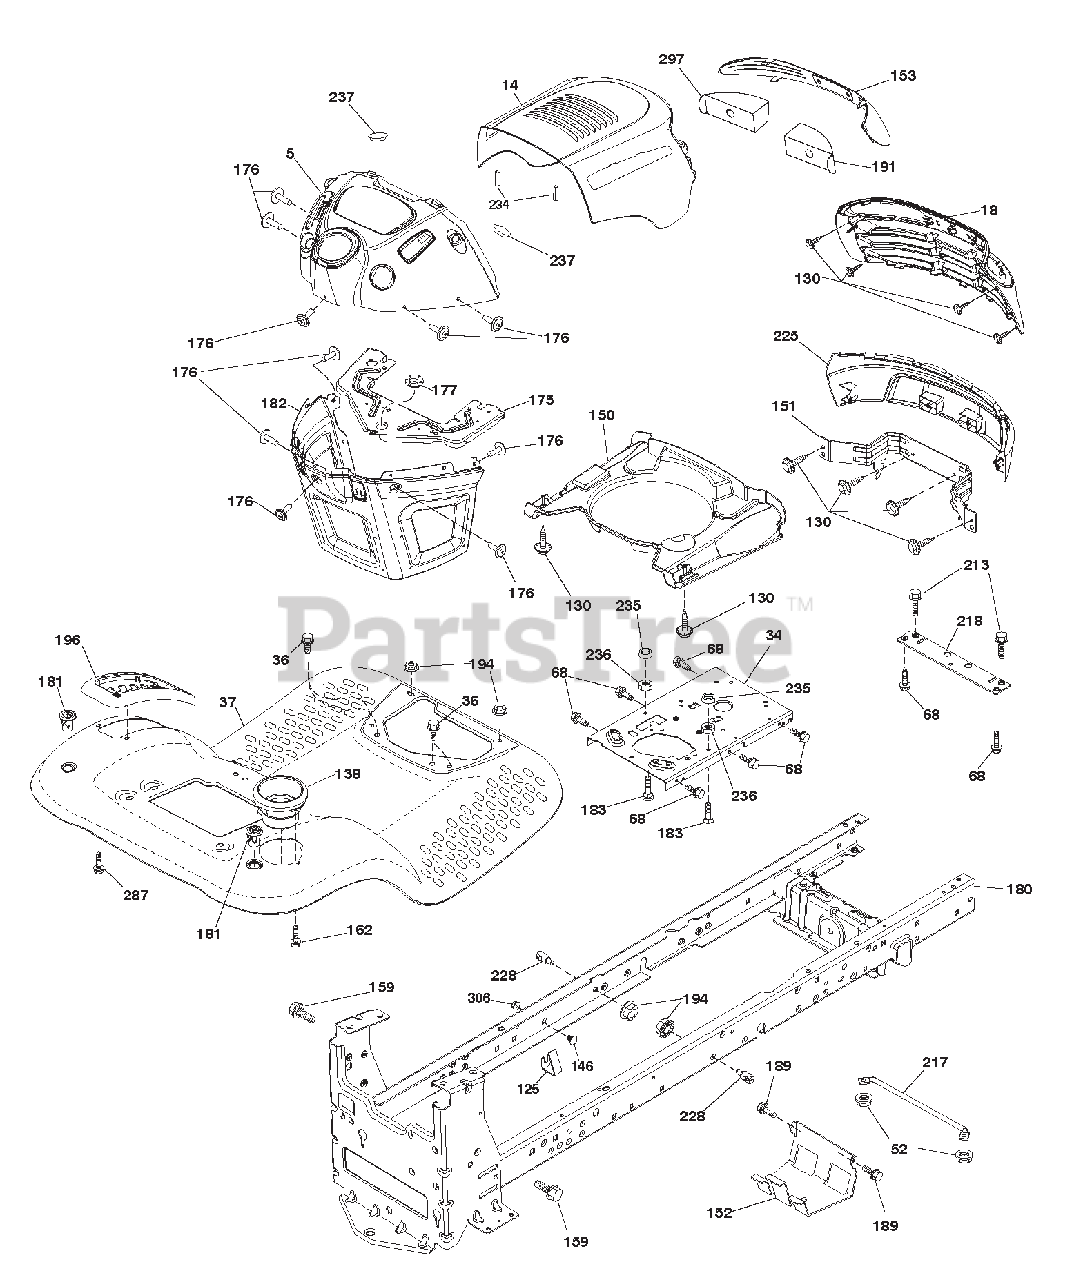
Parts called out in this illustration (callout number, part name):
18	GRILLE
34	PLATE.ENGINE.WELDED.CHASSIS
36	SCREW.5/16-18X3/4.SMGML.TAP/R
37	FENDER TLT W/CPH W/FW 422
52	Nut, Hex, Crownlock 5/16-18
68	SCREW.THDROL.5/16-18 X 1/2TYTT
125	CLIP.FUEL.LINE
138	CUPHOLDER TL TEX 428
150	AIR DUCT.INTAKE.B&S
151	Bracket Pivot
152	SHIELD.BROWNING.W/TEX
153	LENS, ARIENS
159	SCREW.HEXWSH THDR3/8-16X3/4.BL
162	SCREW.HEX.WSH.HI-LO.1/4X1/2UNC
175	CROSSMEMBER.LT
176	SCREW.#10-24X5/8.RND.QUDRX.GIM
177	BUSHING.STEERING.LT
180	CHASS WLDMT TL 12 GA/2PC 18/22
181	BUSHING MNT FEND CRGO BLK TEX
182	DASH LOWER
183	BOLT.FIN.HEX.5/16-18 UNC X1-1/
189	SCREW.5/16-18X3/4.SMGML.TAP/BL
191	INSERT REFLECTIVE RH
194	Nut, Lock Hex Flange 5/16-18 u
196	CONSOLE ASM.DECKLFT.BL/RBT.TLT
213	Bolt, Hex Head 5/16-18 x 3/4
217	ROD.PIVOT.HOOD
218	X-PIECE.HOOD.STOP.NON/STEALTH
225	BUMPER
228	STUD.FASTNER.W/'D'ANTI-ROTATIO
234	BUMPER HOOD
235	SPACER.FENDER
236	NUT.CENTER LOCK.5/16-18 UNC
237	PLUG.MOUNT.CARGO
287	SCREW.HEX.WASHEAD.1/4-20 X 3/8
297	INSERT REFLECTIVE LH
306	Nut, Hex, Flangelock 3/8-16
